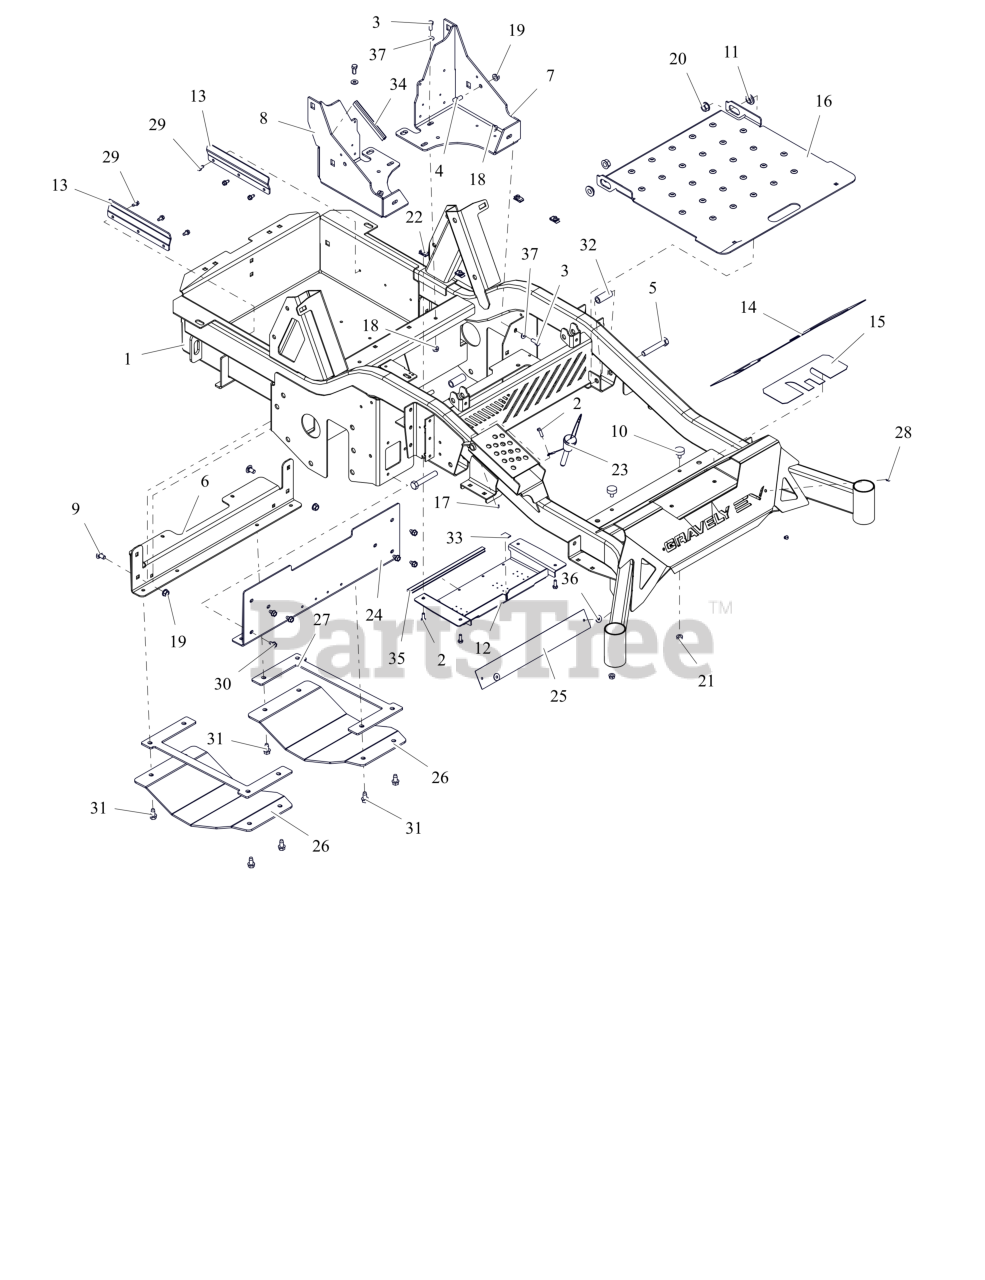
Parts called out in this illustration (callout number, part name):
1	KIT, EV FRAME W/DECALS-GRAVELY
2	BLT, HEX .25-20X.75 G5 ZCC
3	BLT,HEX .31-18X.75 G5 ZCC
4	BLT,HEX .38-16X.75 G5 ZCC
5	BLT, HEX .50-13X3.00 G5 ZCC
6	BRKT, SKID PLATE MTG. (RED)
7	BRKT, SUPPORT ROPS -LH (RED)
8	BRKT, SUPPORT ROPS-RH (RED)
9	BLT, RHSSN .38-16X.75 G5 ZCC
10	BUMPER, RUBBER
11	BSHG-FLG .515X.750X.310X1.120
12	COVER, BOTTOM ACCESS -OPEN (RED)
13	DEFLECTOR, BATTERY -EV (RED)
14	GRIP, FRONT
15	GRIP, TAPE FRONT
16	KIT,ACCESS PANEL W/DECALS-RED
17	NUT-LK-CTR-FLG .25-20 ZC120
18	NUT,LK-CTR-FLG .31-18 GF ZCC
19	NUT-LK-CTR-FLG .375-16 GF ZCC
20	NUT-LK-CTR-FLG .500-13 GG ZCC
21	NUT,SPNLK-FLG .31-18 G5 ZCC
22	NUT-RTNR .25-20X.56
23	PIN, MAGNETIC .50X2.50
24	PLATE, FRONT FRAME (RED)
25	PLATE, BACK FOOT-REST XL
26	PLATE, SKID (BLACK)
27	PLATE, SKID TENSION (BLACK)
28	RIVET, .1875 AL/AL .126-.250
29	SCR-TAP .25-20X.50 HWH ZCC
30	SCR,TAP .312-18X.50 HWH TR ZCC
31	SCR,TAP .375-16X.75 HWH TR ZCC
32	SPACER, .515X.75X1.83
34	STRIP, COWL
35	STRIP, COWL
36	WSHR, RBR W/ADHESIVE .25X.75X.06
37	WSHR, FLT .312X.734X.065 ZCC
